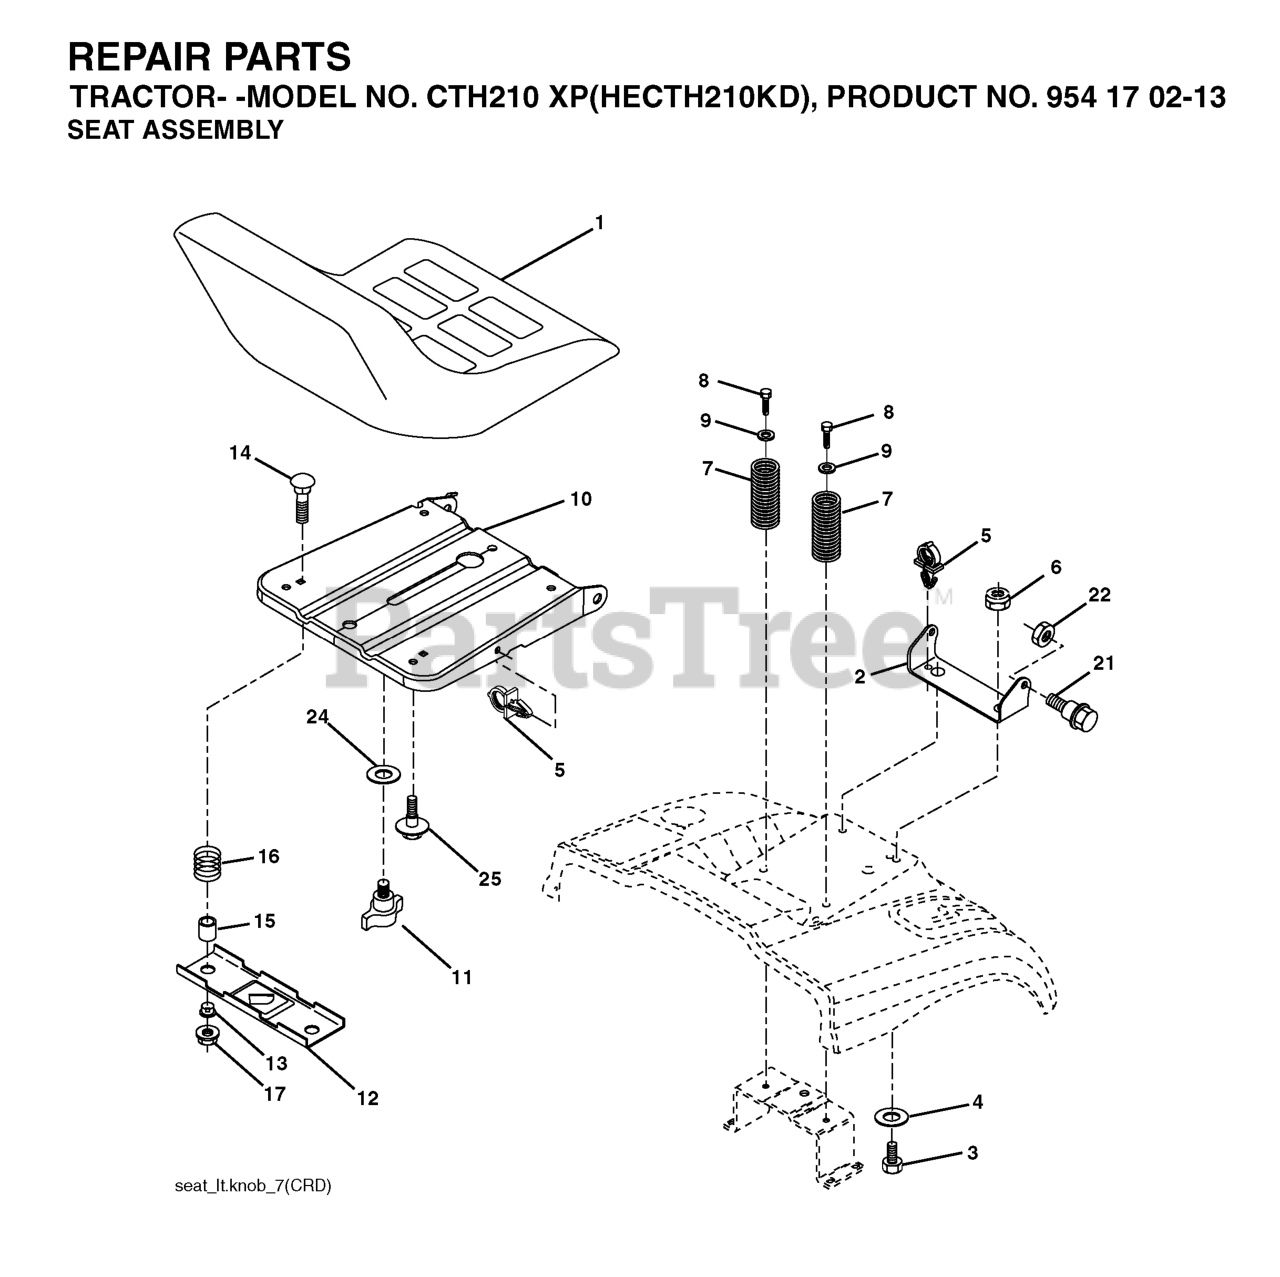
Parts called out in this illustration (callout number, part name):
1	SEAT
2	SEAT PIVOT BRKT
3	BOLT, HEX 3/8-16X1
6	NUT
7	SPRING COMPRESSION
8	SCREW 3/8-16X1
9	WASHER
10	PAN SEAT
11	KNOB.SEAT.ADJ.WINGNUT
12	BRKT SWITCH
14	BOLT.ROUND.HEAD.SQUARE.NECK
15	SPACER SPLIT
16	SPRING COMPRESSED
17	NUT T
21	BOLT.SHOULDER.5/16-18
22	NUT.71038.31-18.HEX.NYLOCK
25	BOLT,SHOULD
